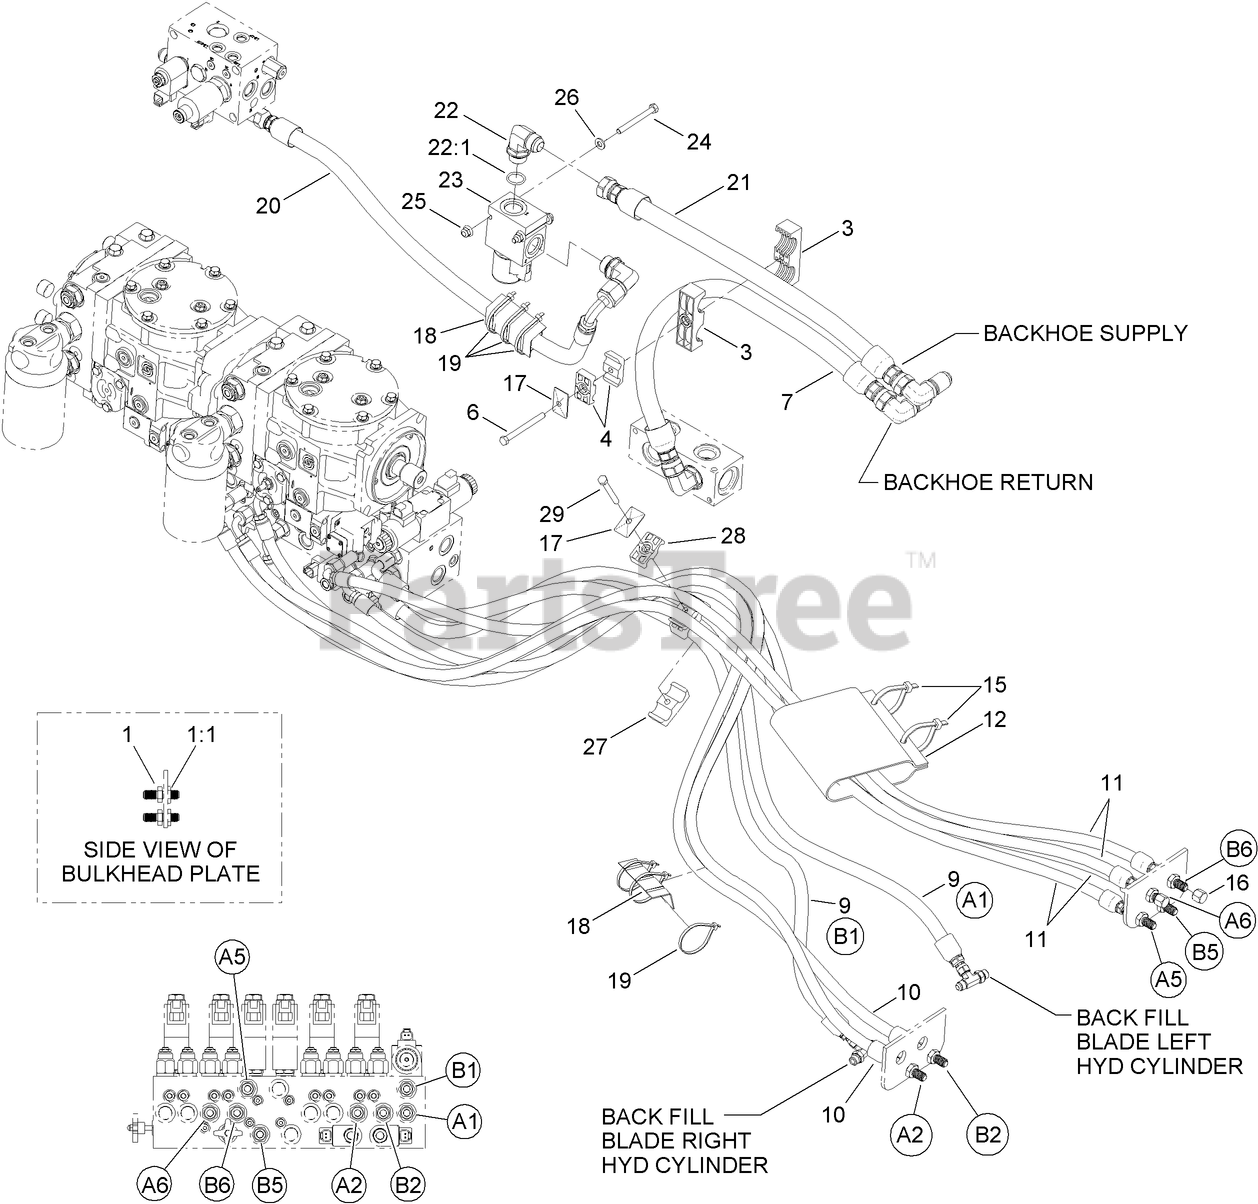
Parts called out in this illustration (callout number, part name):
1	UNION-BULKHEAD
1:1	NUT-LOCK, BULKHEAD
3	CLAMP-TWIN
4	CLAMP-TUBE
6	SCREW-HH
7	HYD HOSE ASM
9	HYD HOSE ASM
10	HYD HOSE ASM
11	HYD HOSE ASM
12	BOOT-HOSE
15	TIE-CABLE
17	COVERPLATE
18	PROTECTOR-HOSE
19	TIE-CABLE
20	HYD HOSE ASM
21	HYD HOSE ASM
22	FITTING-ELBOW, 90 DEG
22:1	O-RING
23	VALVE-BLOCKING
24	SCREW-HH
25	NUT-LOCK, HHF
26	WASHER-PLAIN
27	CLAMP-TUBE
28	CLAMP-TUBE
29	SCREW-HH
